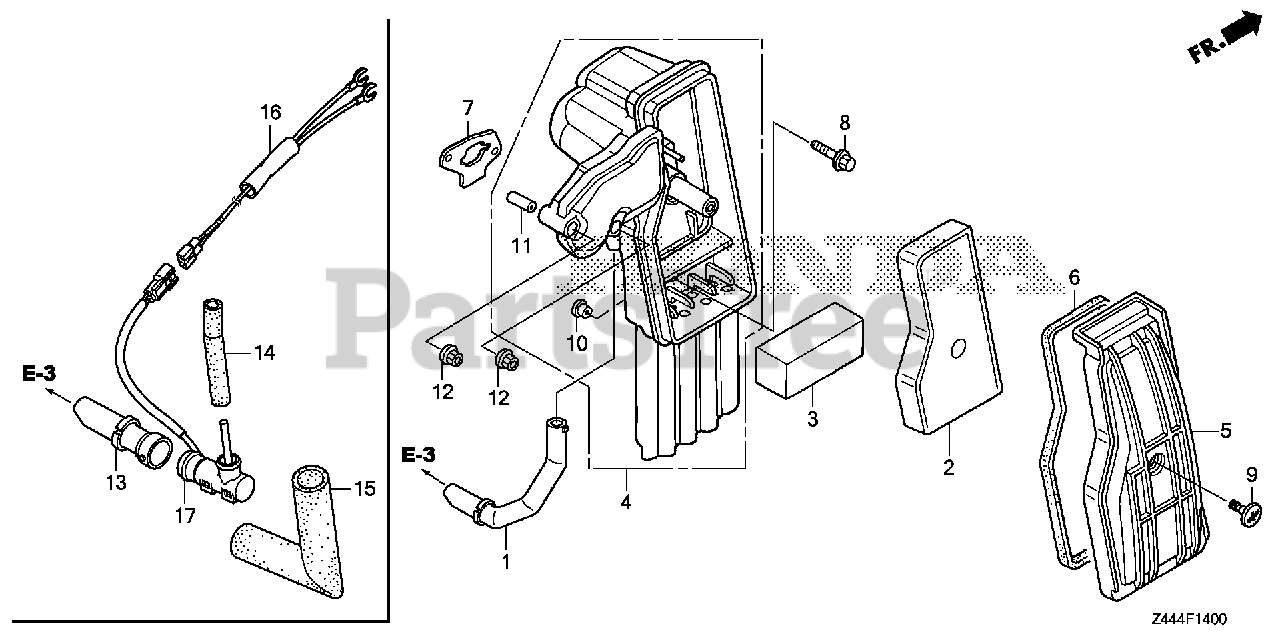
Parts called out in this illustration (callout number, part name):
1	TUBE, BREATHER
2	ELEMENT, AIR CLEANER
3	FILTER (OUTER)
4	HOUSING, AIR CLEANER
5	COVER, AIR CLEANER
6	SEAL A, AIR CLEANER COVER
7	GASKET, AIR IN. JOINT
8	BOLT, FLANGE (5X16)
9	SCREW, SPECIAL (6X16)
10	COLLAR, REFLECTOR SETTING
11	COLLAR, AIR CLEANER
12	NUT, FLANGE (5MM)
